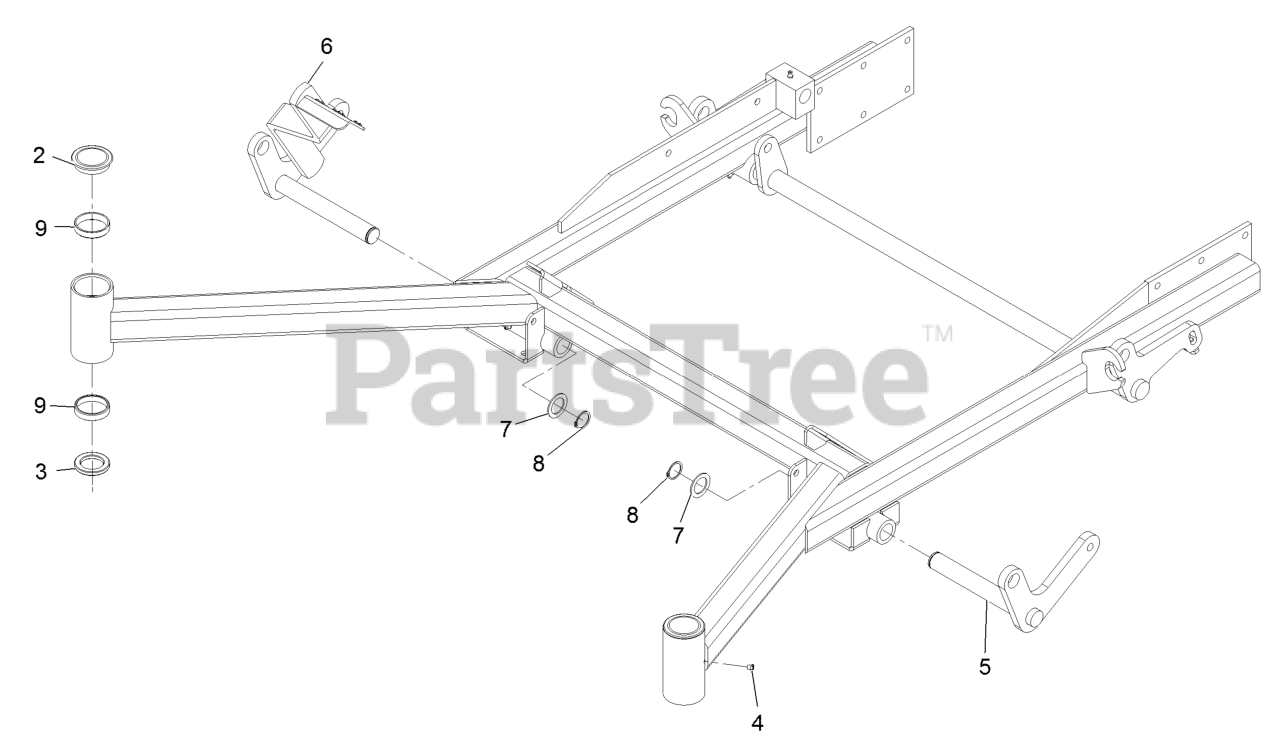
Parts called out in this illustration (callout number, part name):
2	CAP-GREASE
3	SEAL-GREASE
5	WLD,FRONT LIFT SHAFT-LH
6	WLD,FRONT LIFT W/LEVER
7	WASHER-SPACER
8	RING-RETAINING
9	CUP-BEARING
